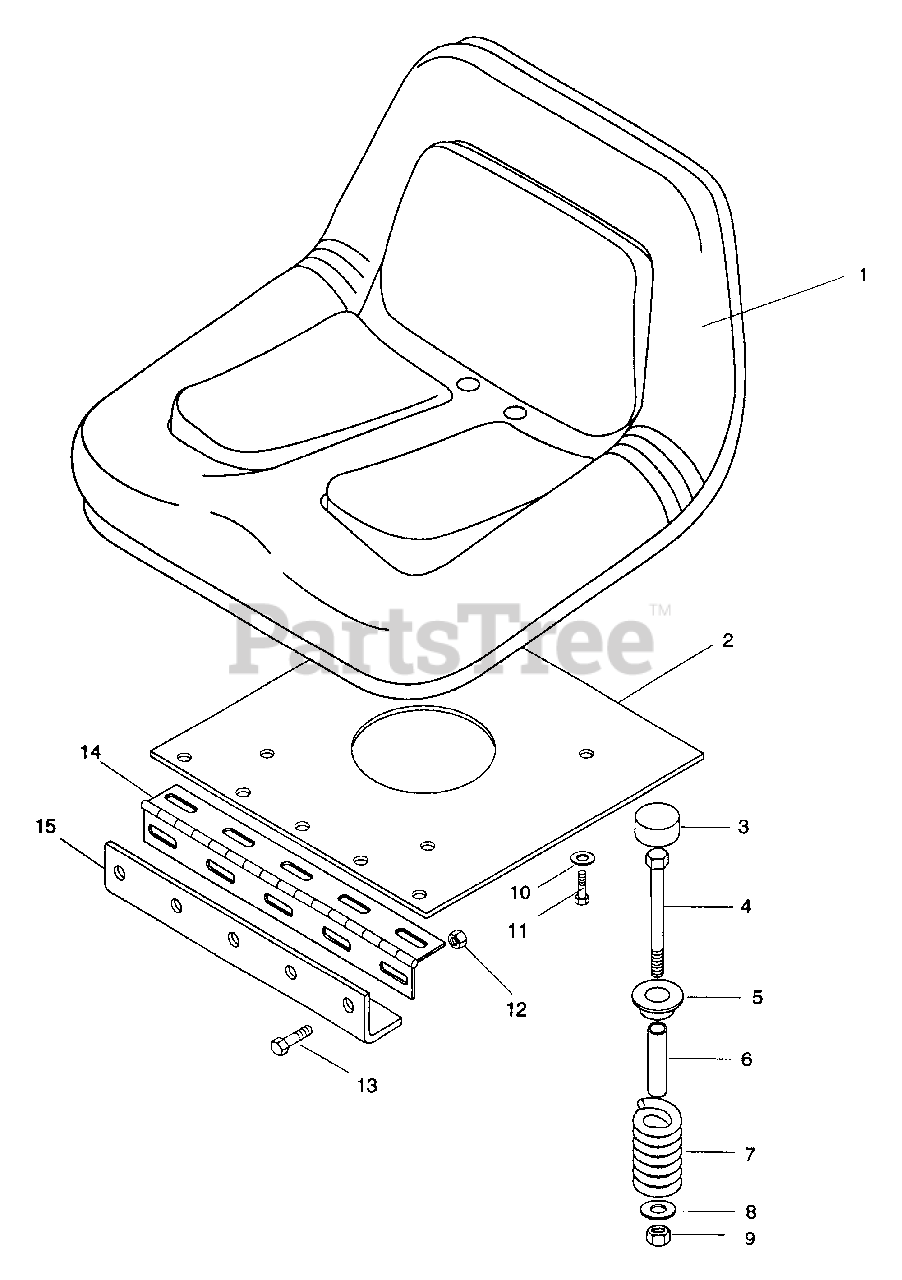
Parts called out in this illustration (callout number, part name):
1	Seat, High Back
2	Plate, Seat Mounting
3	Molded Cap 1.5 OD, 1.0 ID, .44 Thick
4	Bolt, Hex .25-20 x 2.25
5	Cap, Valve Spring
6	Bushing, Split Rolled
7	Spring, Compression
8	Washer, Flat Steel .344 x .688 x .065
9	Nut, Lock Nylon .250-20
10	Washer, Lock .313 x .079
11	Bolt, Hex .31-18 x .625 Gr. 5
12	Nut, Lock Nylon .312-18
13	Bolt, Hex .31-18 x .625 Gr. 5
14	Hinge
15	Bracket, Seat Support
16	Kit, Arm Rest G. Series
